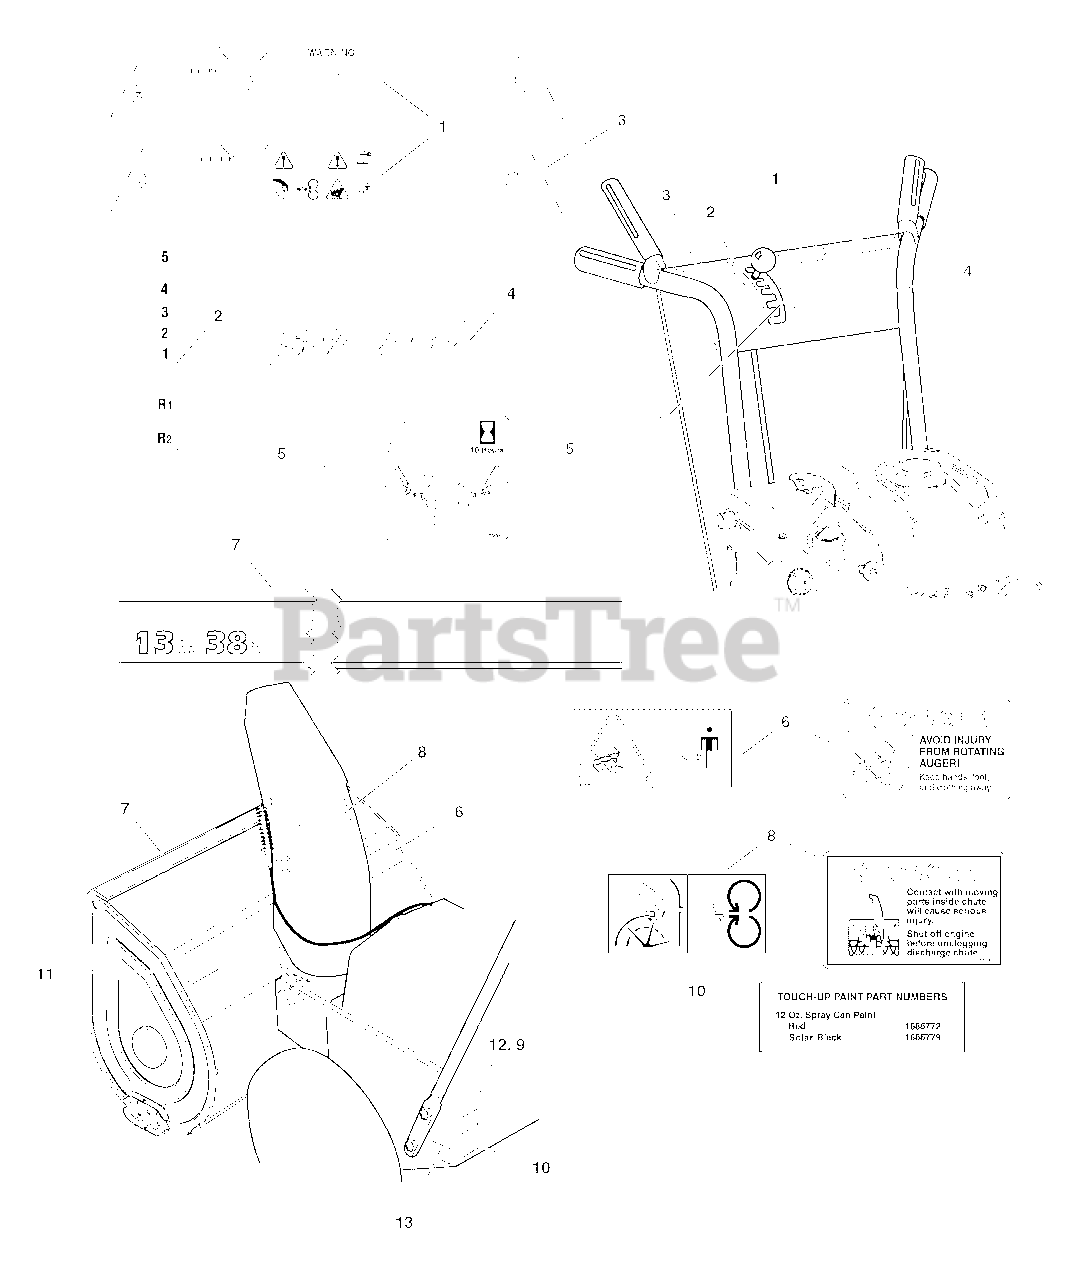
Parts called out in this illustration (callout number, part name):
1	DECAL, Instructions with EZ Turn, L.H.
1	DECAL, Tube Handle, L.H.
2	DECAL, 5 4 3 2 1 R1 R2 Shift Pattern
3	DECAL, Instructions, Auger Control
3	DECAL, Tube Handle R.H.
4	DECAL, Turtle Head/Logo Badge
5	DECAL, Lubrication
6	DECAL, Danger Avoid Injury from Auger
7	DECAL, Stripe Snapper Professional 38"
8	DECAL, Danger Auger, Use Snow Stick
9	MYLAR OVERLAY
10	DECAL, Touch Up Paint
11	DECAL, OPEI Certified (Not a part sale item)
12	DECAL, ID Plate
13	DECAL, Patent Snowthrower
